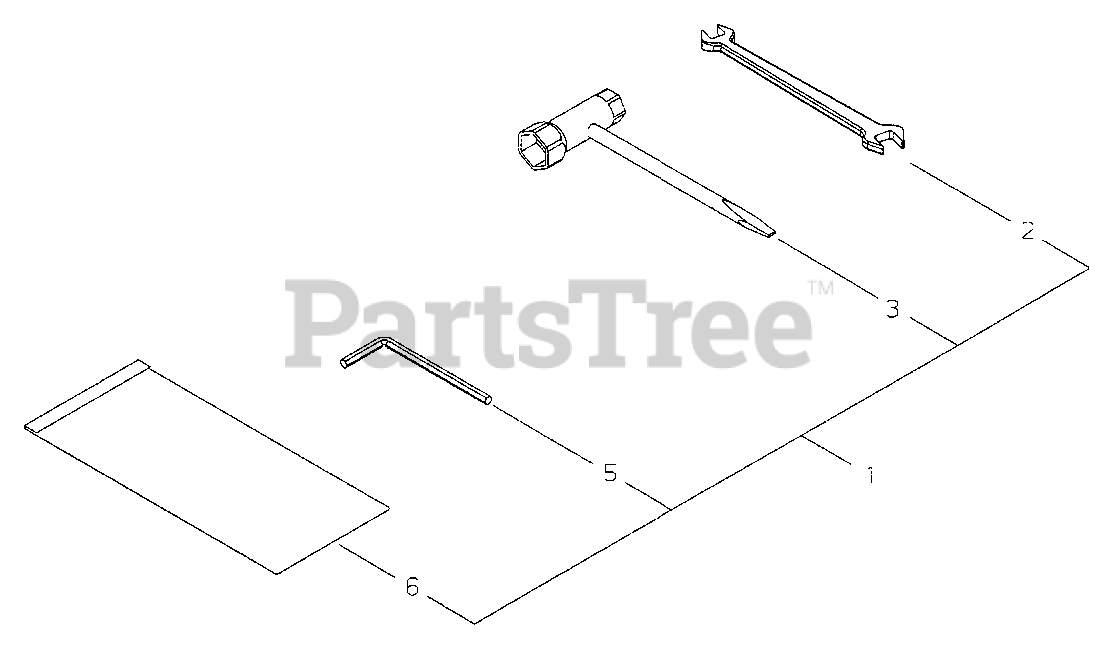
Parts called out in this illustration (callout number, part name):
1	TOOL KIT, SERVICE
2	SPANNER 8×10
3	T-WRENCH 16×13
4	WRENCH, ALLEN 4 MM
5	BAG, TOOL
